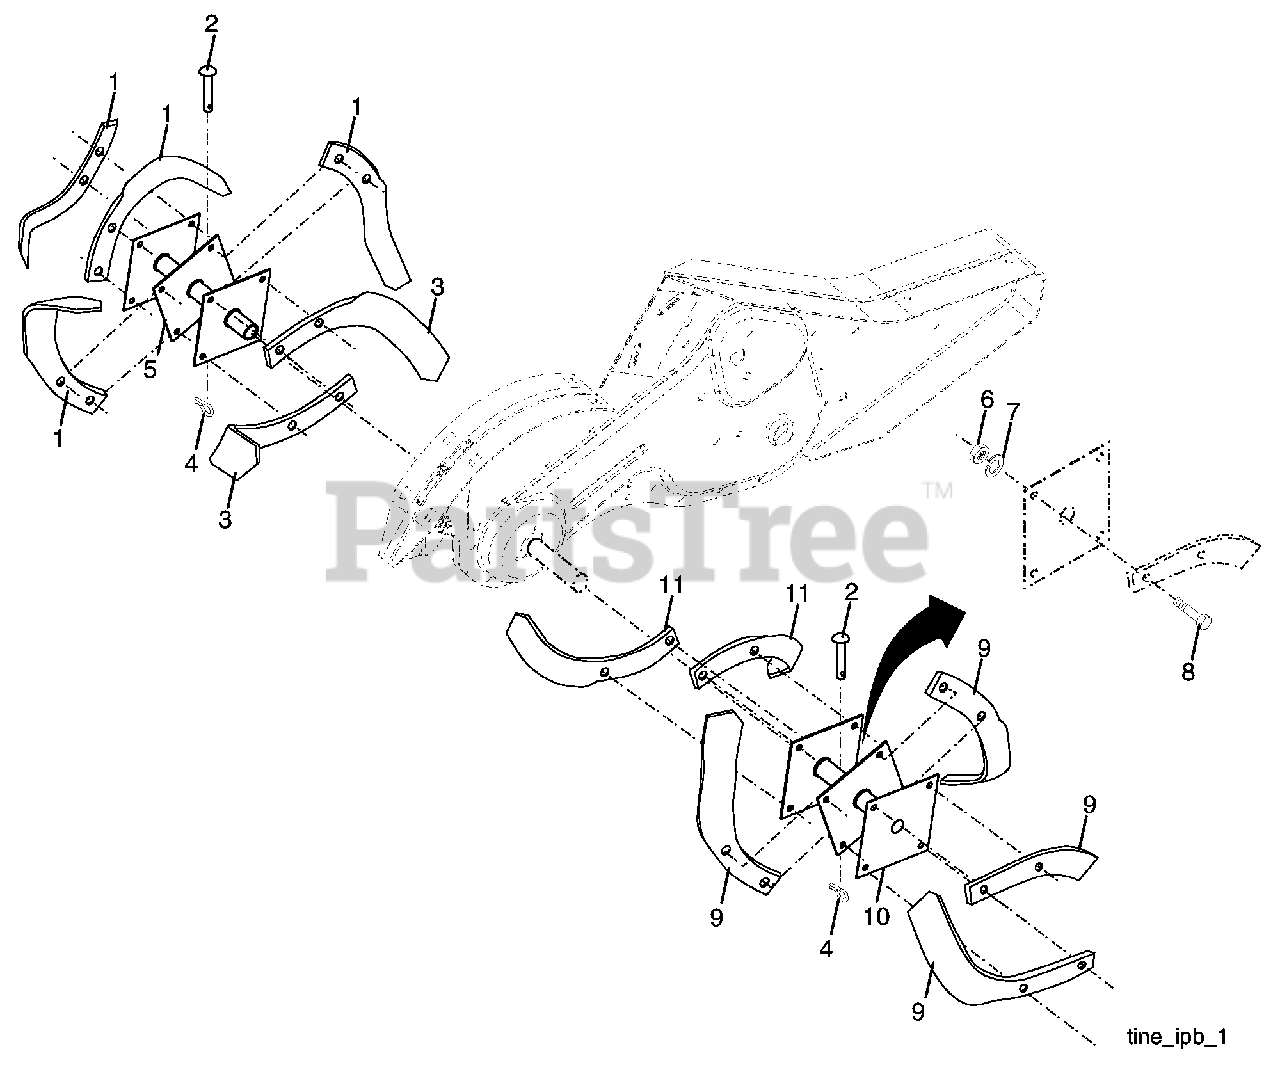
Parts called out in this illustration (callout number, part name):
1	Tine, Outer, L.H.
2	Clevis Pin
3	Tine, Inner, L.H.
4	Retainer, Spring Zinc
5	Assembly, Hub and Plate, L.H.
6	Nut, Hex 3/8-24
7	Washer, Lock 3/8
8	Bolt, Hex 3/8-24 x 1
9	Tine, Outer, R.H.
10	Assembly, Hub and Plate, R.H.
11	Tine, Inner, R.H.
